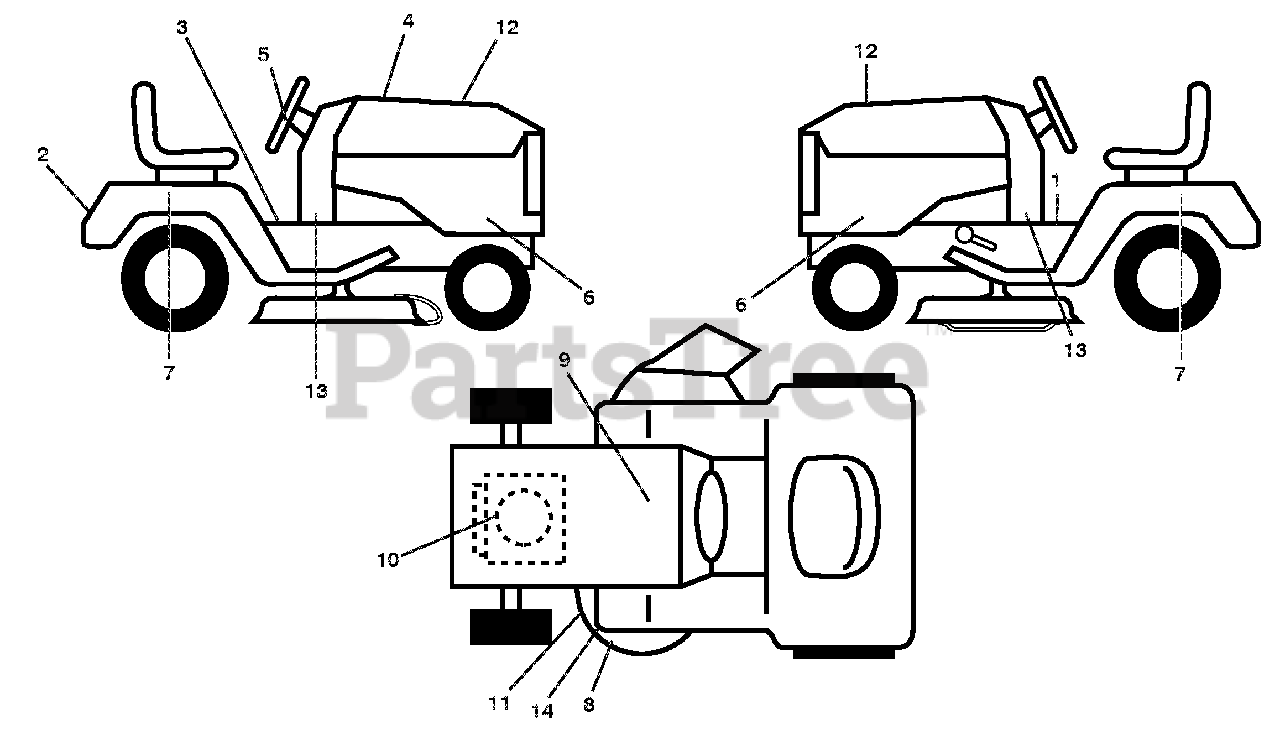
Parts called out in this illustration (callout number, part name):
1	DECAL.WARNING.START
2	DECAL.FENDER.REAR.ARIENS
3	DECAL.FENDER
4	DECAL.REPLACEMENT
5	DECAL.WHEEL.STEER.ARIENS
6	DECAL.SDPNL.PWRDBY B&S.ARIENS
7	DECAL.FENDER.SIDE.HYDRO.ARIENS
8	DECAL.MOWER.SCH
9	DECAL.BAT.DAN/POI P/L SYM.WPN
10	DECAL.ENGINE
11	DECAL.MOWER.CAUTION
13	DECAL.LWDASH
14	DECAL.WARNING.KEEP.HAND.AWY
